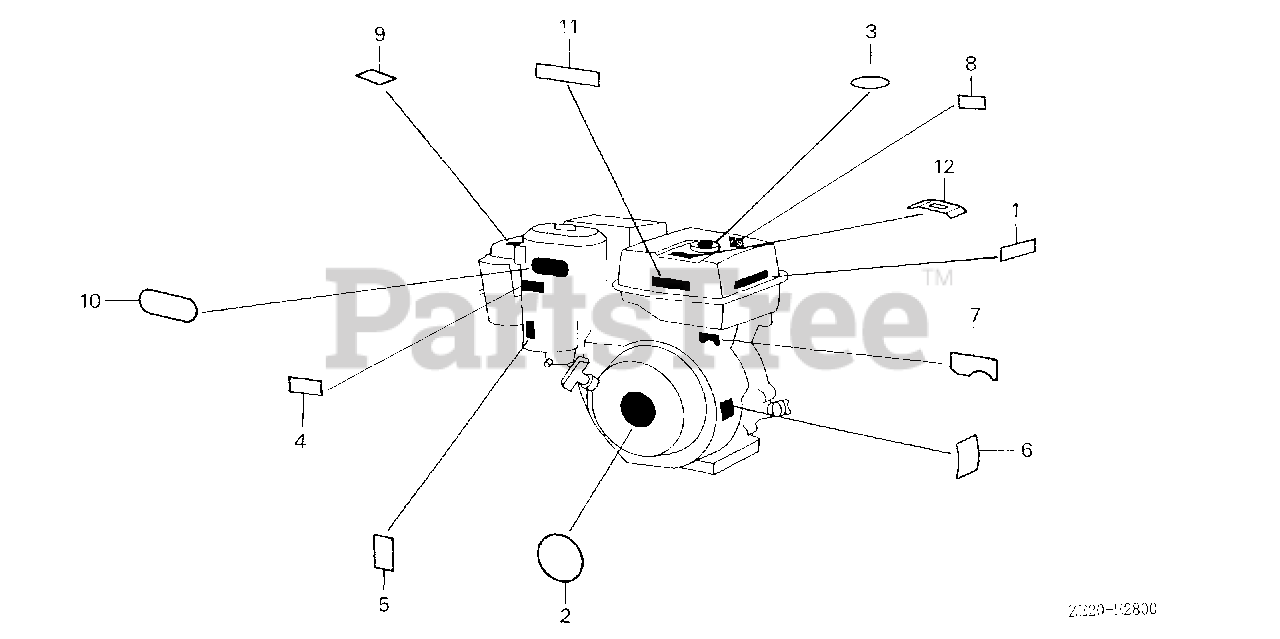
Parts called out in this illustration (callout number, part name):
2	EMBLEM (EXTERNAL-ALERT)
3	MARK, CAUTION
5	MARK, CHOKE (ORANGE)
7	MARK, OIL ALERT (EXTERNAL)
